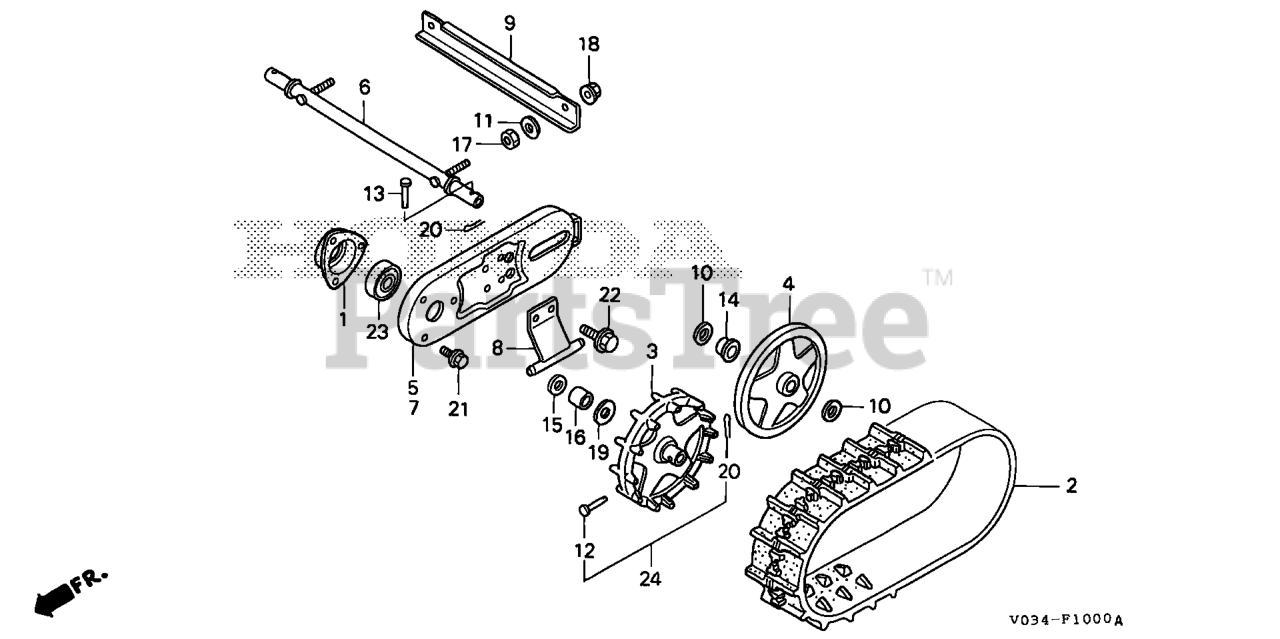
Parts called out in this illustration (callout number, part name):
1	HOLDER, WHEEL SHAFT BEARING
2	CRAWLER (12-60X21)
3	SPROCKET, CRAWLER
4	ROLLER, CRAWLER
5	PLATE, R. CRAWLER
6	PIPE, CRAWLER
7	PLATE, L. CRAWLER
8	GUIDE, CRAWLER
9	BAR, CRAWLER PLATE
10	WASHER, PLAIN (22MM)
11	WASHER, PLAIN (10MM)
12	PIN (6.2X38)
14	COLLAR, CRAWLER PIPE
15	COLLAR, R. WHEEL SHAFT
16	COLLAR, CRAWLER SPROCKET
17	NUT, FLANGE (10MM)
17	NUT, HEX. (10MM)
18	NUT, FLANGE (10MM)
19	WASHER, PLAIN (20MM)
20	PIN, COTTER (3.0X18)
21	BOLT, FLANGE (6X12) Use up to Engine SN 1543277.
22	BOLT, FLANGE (8X14)
23	BEARING, RADIAL BALL (6004UU)
24	PIN SET, CRAWLER
